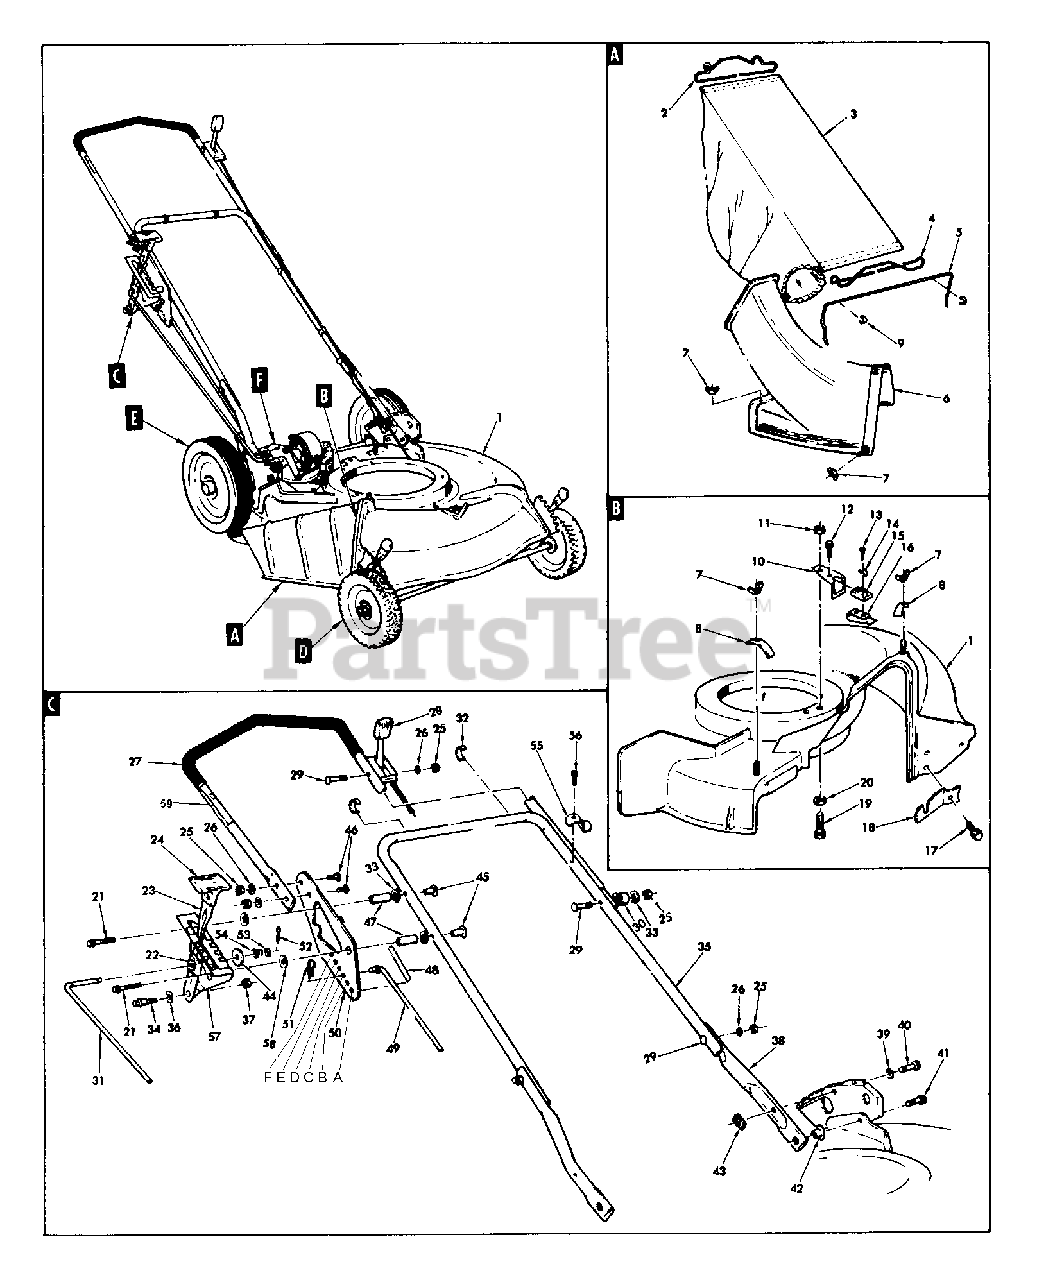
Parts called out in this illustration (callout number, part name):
1	Deck Assembly
2	Rear Wire
3	Grass Bag
4	Front Wire
5	Roll Bar
6	Bag Chute Assembly
7	5/16-18 Wing Nut
8	Clamp
9	Nylon Ring
10	Ground Strap
11	5/16-24 Hex Lock Nut
12	SCREW, #10-24 x 1/2" Hex Washer Self-Tap (Torx)
13	10-18 x 3/4 Screw
14	Tab Washer
15	Insulator
16	Interlock
17	5/16-18 x 5/8 SEMS
18	Side Bracket
19	5/16-24 x 1 5/8 CS Grade 5
20	5/16 SAE Flat Washer
21	Hex Hd. Mach. Screw
22	Wear Block
23	Shift Handle
24	Shift Knob
25	1/4-20 Hex Nut
26	1/4 Internal Tooth lock washer
27	Upper Handle Ass'y.
28	Throttle Control
29	1/4-20 x 1 1/2 Car. Bolt
30	Spacer
31	Shift Rod
32	Ring, Nylon
33	Fender Washer 1 x 5/16 x 1/16
34	5/16 Shoulder Screw
35	Lower Handle Pivoting
36	Spring Washer
37	5/16-18 Jam Nut
38	Lower Handle Stationary
39	5/16 Internal-External tooth lock washer
40	HWST, 5/16C X3/4 YZ
42	5/16-18 Dot "T" Nut
43	5/16-24 Weld Nut
44	Friction Washer
45	Tee Nut, R.B.
46	1/4-20 x 3/4 Carriage
49	Rod Release
50	Bracket, Handle
51	Hair Pin, plated
52	Cotter Pin, 1/8 x 3/4
53	3/8 SAE Washer
54	Shift Spring
55	Bracket, Handle L.H.
56	Screw, 10-18
57	Detent
58	1/4 SAE Washer
59	Handle Decal
